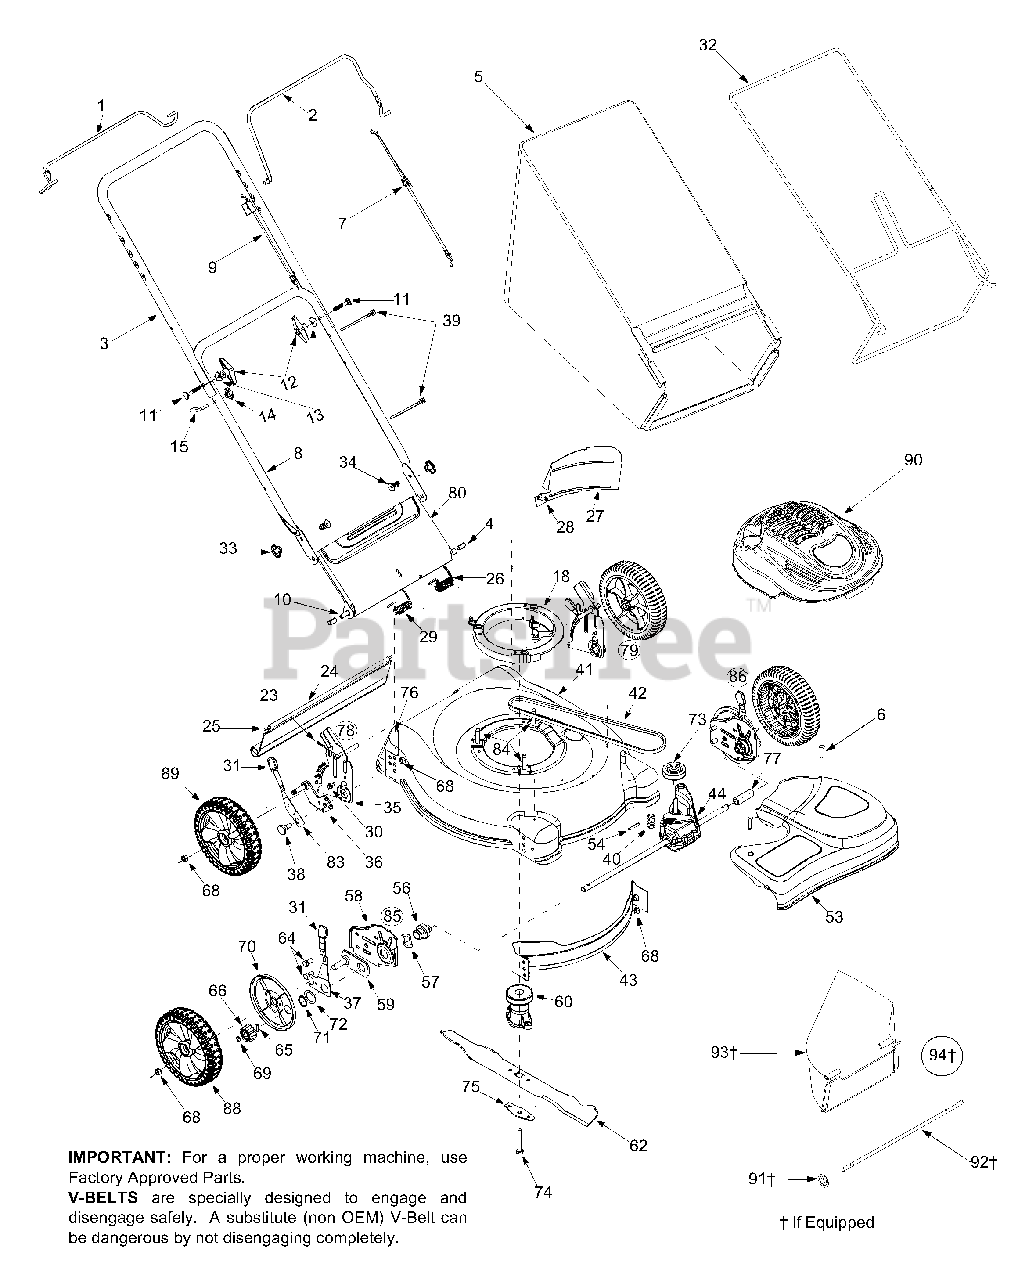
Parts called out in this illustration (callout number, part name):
1	Lower Bail Handle
4	Spacer.390OD x.810ID x.950"
5	Grass Bag
6	Shoulder Screw
7	Control Cable: 50.56"
9	Drive Cable
10	Rear Door Pivot Rod
11	Carriage Bolt
12	Handle Knob
13	Saddle Washer
14	Wing Nut
15	Rope Guide
18	Engine Spacer Assembly
23	Hairpin Clip
24	Rear Trail Shield
25	Trail Shield Wire
26	Torsion Spring LH
28	Scr. AB 1/4-14 x 0.625"
29	Torsion Spring RH
30	Hex Scr. w/ Wash. 1/4-20 x 0.625"
31	Knob
33	Wing Nut
34	Hex Carriage Screw
35	Handle Bracket RH
36	Pivot Arm Assembly RH
37	Front Lever RH
38	Shoulder Screw
39	Cable Tie
40	Belt Tension Spring
41	Rear Discharge Deck: 21"
42	V-Belt
53	Front Drive Cover: Yellow
54	Roll Pin
56	Bearing Assembly
57	Wave Washer
60	21" One Piece Blade Adapter
62	Mulching Blade w/ Star: 21"
64	Hex Screw
65	Dowel Pin
66	Gear 14T RH
68	Hex Nut
69	Snap Ring
70	Wheel Dust Cap
71	Snap Ring
72	Washer DD 1.5" O.D.
73	Input Pulley
74	Hex Bolt
75	Bell Blade Support
77	Slev. Spacer LH
78	Handle Brkt Assembly RH Compl.
79	Handle Brkt Assembly LH Compl.
80	RD Chute Door
83	Spring Lever
84	TT Screw
85	Height Adj. Assembly RH Compl.
86	Height Adj. Assembly LH Compl.
88	Front Wheel Complete, 8x1.8
89	Rear Wheel Complete, 8x1.8
90	Engine Shroud
91	Nut: Spd.3125ID
92	Rod
93	Side Discharge Adapter
94	Chute Deflector Complete
